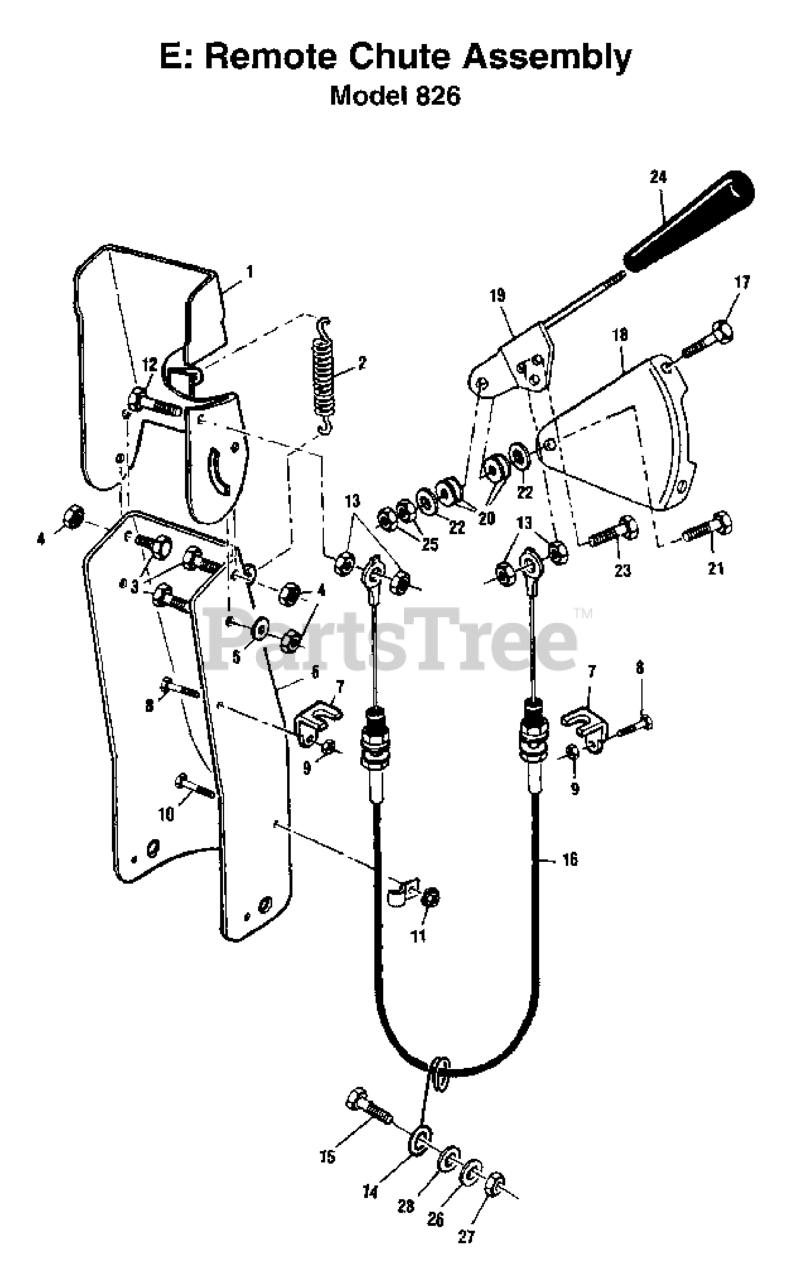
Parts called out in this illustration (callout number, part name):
4	LOCKNUT
9	LOCKNUT
13	NUT.CROWNLOCK.1/4
26	WASHER.LOCK.HVY.HLCL.SPR.5/16
